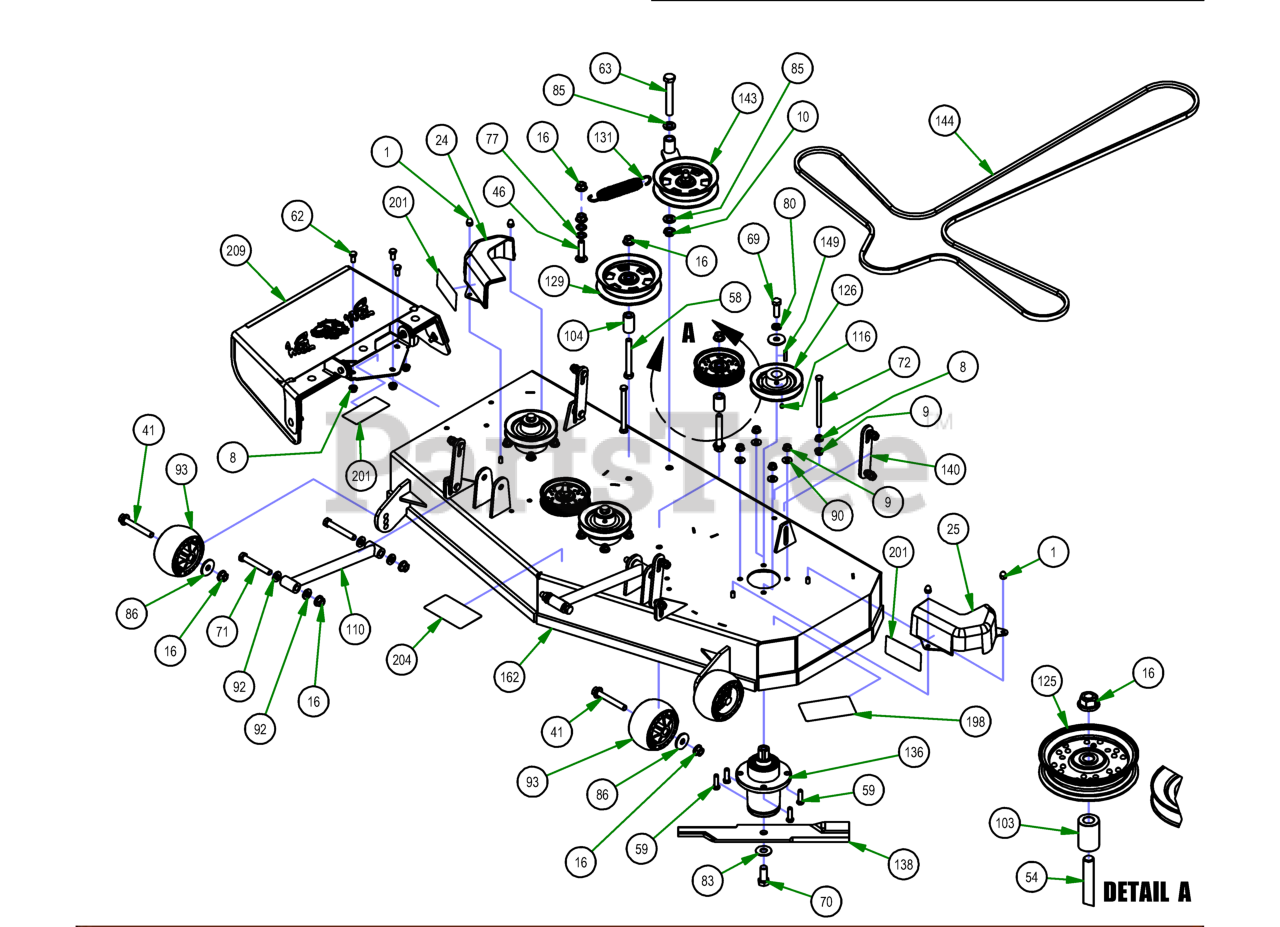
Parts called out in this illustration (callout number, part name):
1	5/16-18 ACORN NUT HIGH-CROWN ZC
8	3/8-16 HEX SERRATED FLANGE NUT HARD/ZINC
9	3/8-16 NYLON INSERT FLANGE LOCKNUT (GR.F) ZINC
10	5/8-11 NYLON INSERT JAM LOCKNUT ZINC
16	1/2-13 NYLON INSERT FLANGE LOCKNUT ZINC
24	pulley cover chute side
25	pulley cover non-chute side
41	1/2-13 X 90MM HEX FLANGE BOLT W/SHOULDER (GR.8) ZINC
46	1/2-13 X 2 CARRIAGE BOLT ZINC
54	1/2-13 X 3-1/2 HEX FLANGE BOLT (GR.8) ZINC
58	1/2-13 X 4 HEX CAP SCREW (GR.8) ZINC YELLOW
59	3/8-16 X 1-1/4 HEX CAP SCREW (GR.5) ZINC
62	3/8-16 X 3/4 HEX CAP SCREW (GR.5) ZINC
63	5/8-11 X 4 HEX CAP SCREW (GR.8) ZINC YELLOW
69	1/2-20 X 1-1/2 HEX CAP SCREW (GR.5) ZINC
70	5/8-18 X 1-1/2 HEX CAP SCREW (GR.8) ZINC YELLOW
71	1/2-13 X 3-1/2 HEX CAP SCREW (GR.5) ZINC
72	3/8-16 X 5-1/2 HEX CAP SCREW (GR.5) ZINC
77	.517 SQ WDTH ID X .937 OD X .060 THICK F/W PHOS/OIL
80	1/2 SPLIT LOCKWASHER (GR.8) ZINC/YELLOW
83	5/8 USS FLAT WASHER (1-3/4" OD) GR.8 ZINC YELLOW
85	.635 ID X 1.120 OD X .140 THICK FLAT WASHER NYLON
86	1/2 BELLEVILLE WASHER (1-5/8 OD X .140 THK) ZINC
90	5/16 USS FLAT WASHER (7/8 OD) ZINC
92	.505 ID X 1.000 OD X .125 THICK FLAT WASHER NYLON
93	Deck Wheel
103	.502 ID X .750 OD X 1.500 Long Spacer
104	1 3/4" Pulley Spacer
110	MZ/ZT Deck Locator
116	5/16-24 X 1/4 SOCKET SET SCREW (CUP PT) PLAIN
125	4 3/4 Idler Pulley - ABFI-76
126	5" Spindle Deck Pulley
129	5-3/4 Idler Pulley
131	Deck Idler Spring
136	Spindle Assembly
138	48" ZT/Mav/Compact Outlaw Blade with Fusion
140	Deck Hanger Assembly
143	2017 54"/48" Deck Idler Assembly
144	B147 Deck Belt
149	1/4 X 1 SQ MACHINERY KEY 1018 STL PLN
162	2017 48" ZT Deck Welded Assembly
198	2018 48" Deck Decal
201	Danger Decal-Spindle/Discharge
204	Deck Belt Route Decal
209	ZT Chute Assembly
